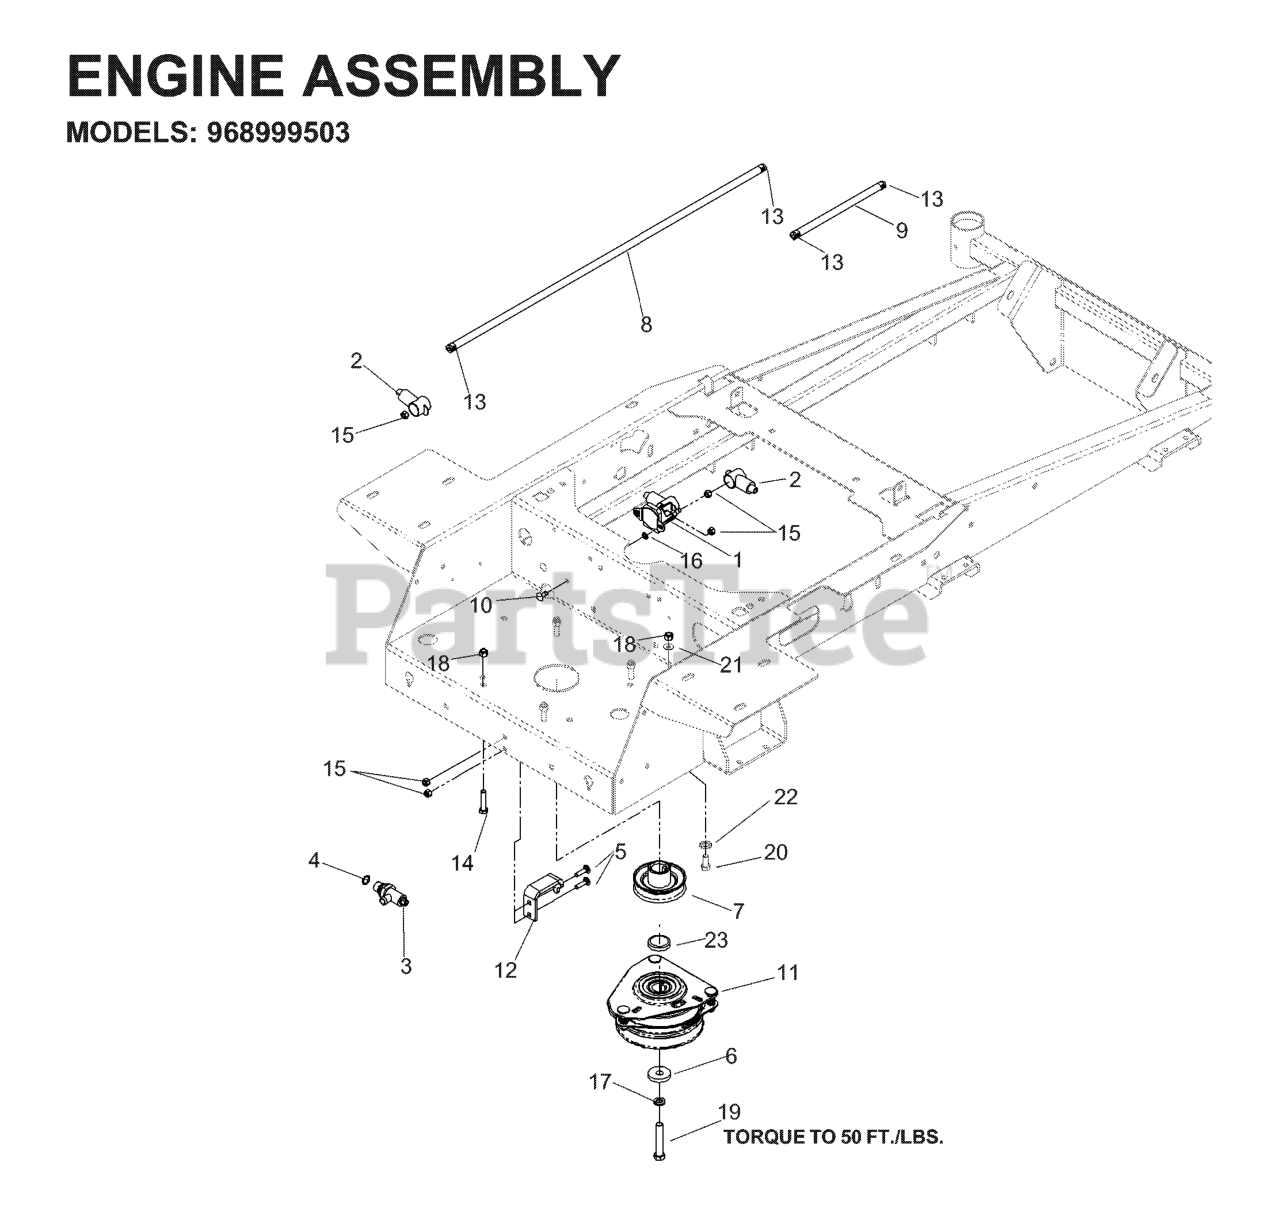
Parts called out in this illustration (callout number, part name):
3	VALVE ASSEMBLY
5	RHSNB, 1/4-20 X 1, GR5
6	CLUTCH, WASHER
7	PULLEY, ENGINE
8	FUEL LINE 24"
9	FUEL LINE 5"
10	RHSSNB, 1/4-20X5/8
11	CLUTCH, OGURA - 90 FT/LB
12	CLUTCH TIE DOWN
13	HOSE CLAMP
14	CAPSCREW 5/16 X 1/1/2 HEX HEAD
15	NUT.1/4-20.HEX.NYLOC.ZD
16	WASHER 1/4 INT TOOTH
17	WASHER 7/16 LOCK
18	NUT 5/16 NYLOC
19	BOLT 7/16F X 2 1/2
20	HCS 5/16C X 3/4
21	WASHER 5/16 FLAT
22	WASHER 5/16 EXT STAR
23	SPACER, ENGINE, PULLEY
